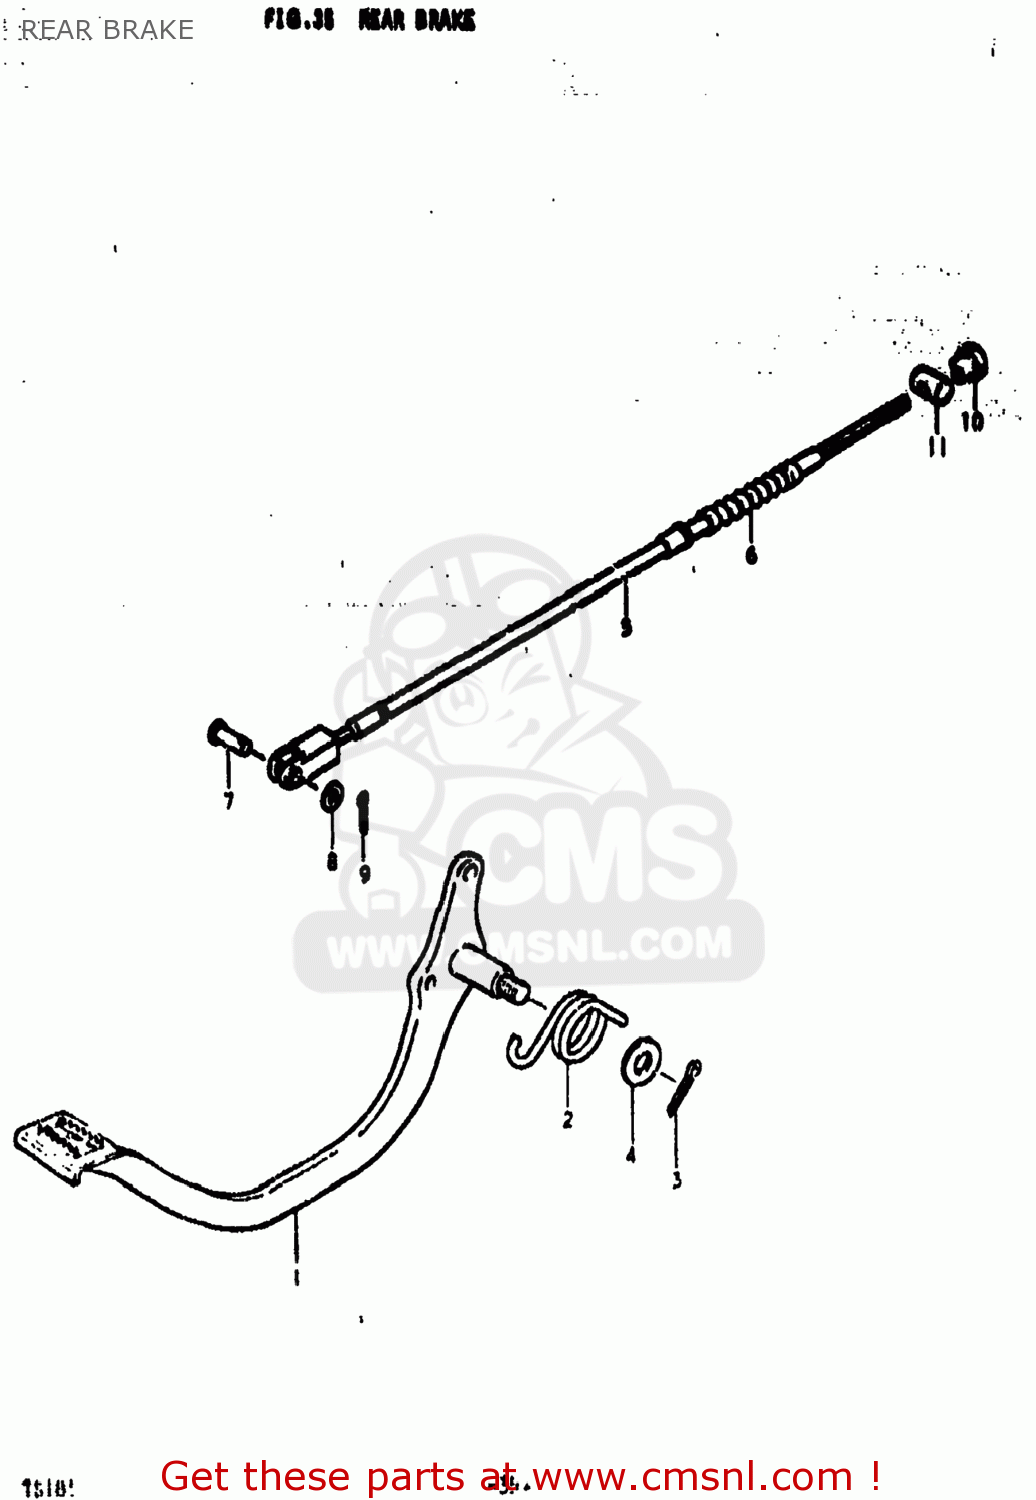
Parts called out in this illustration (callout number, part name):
1	PEDAL,BRAKE
2	SPRING
3	COTTER PIN
4	SPACER(15.2X26X33)
5	CABLE,RR BRAKE
6	SEAL,DUST
7	PIN(L:17.5)
8	WASHER
9	PIN
10	NUT
11	PIN(11X18)
